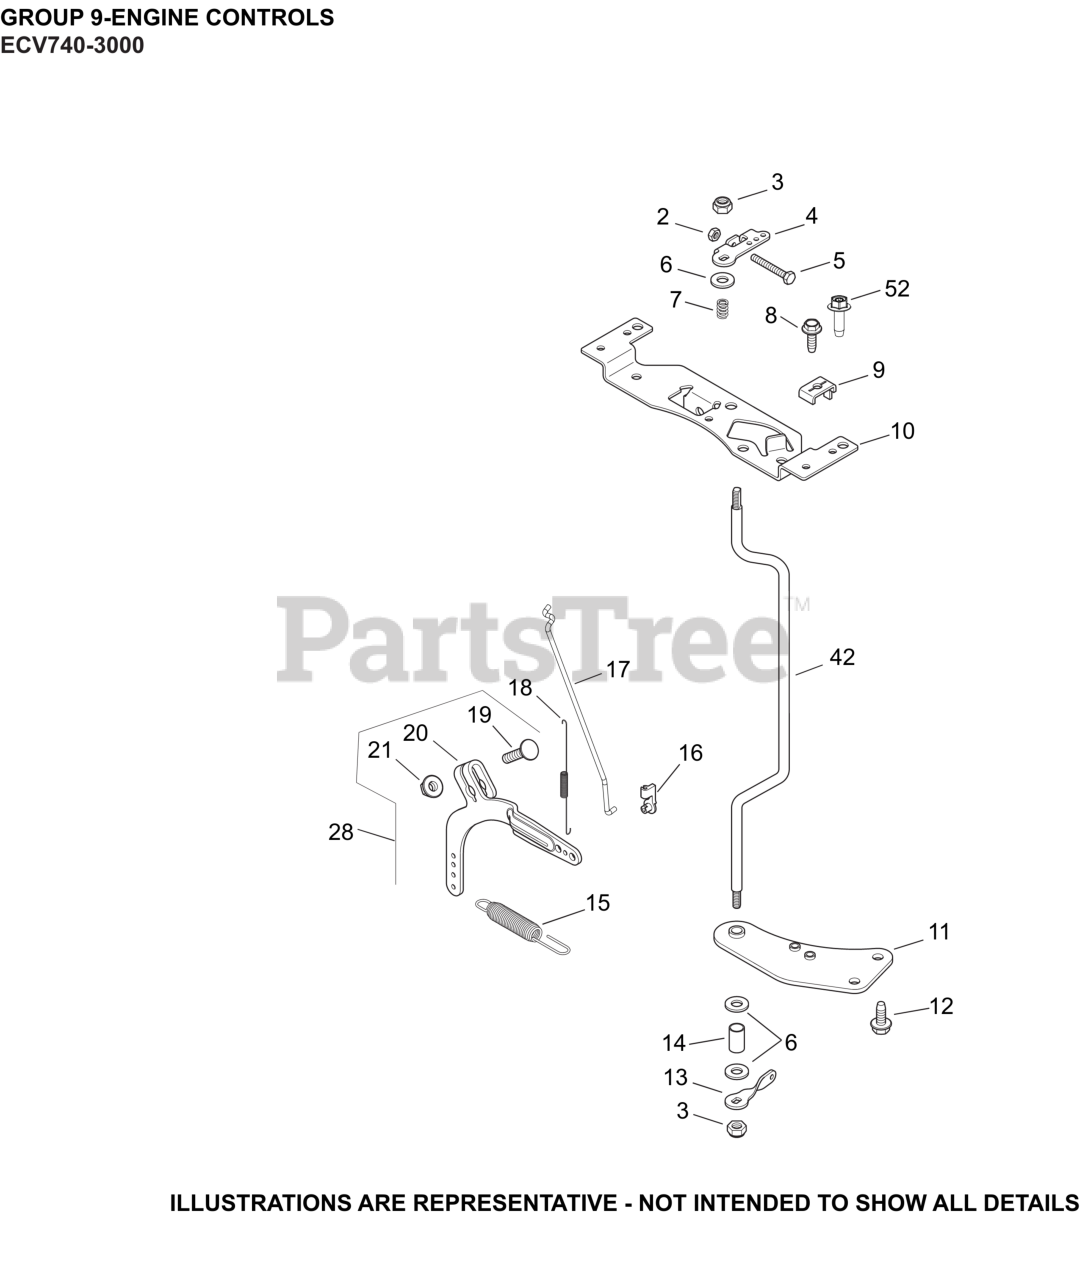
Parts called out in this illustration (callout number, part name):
2	NUT, M4X0.7
3	NUT, LOCK M6X1.0
4	LEVER, THROTTLE CONTROL
5	SCREW, CAP M4X.7X30
6	WASHER, FLAT 1/4"
7	SPRING, THROTTLE SHAFT
8	SCREW, MATHREAD M5 X 0.8 X 16
9	CLAMP, CABLE
10	BRACKET, CONTROL
11	BRACKET, THROTTLE SHAFT
12	SCREW, THREAD FORMING
13	LEVER, THROTTLE CONTROL
15	SPRING, GOVERNOR (RED)
16	BUSHING, THROTTLE LINKAGE
17	LINKAGE, THROTTLE
18	SPRING, LINKAGE
19	BOLT, RD HD SQ NECK M6X1.0X25
20	LEVER, GOVERNOR - (#2409069S)
21	NUT, FLG M6X1.0
28	LEVER, GOVERNOR ASSEMBLY
42	THROTTLE CONTROL SHAFT
52	SCREW, THREAD FORMING
